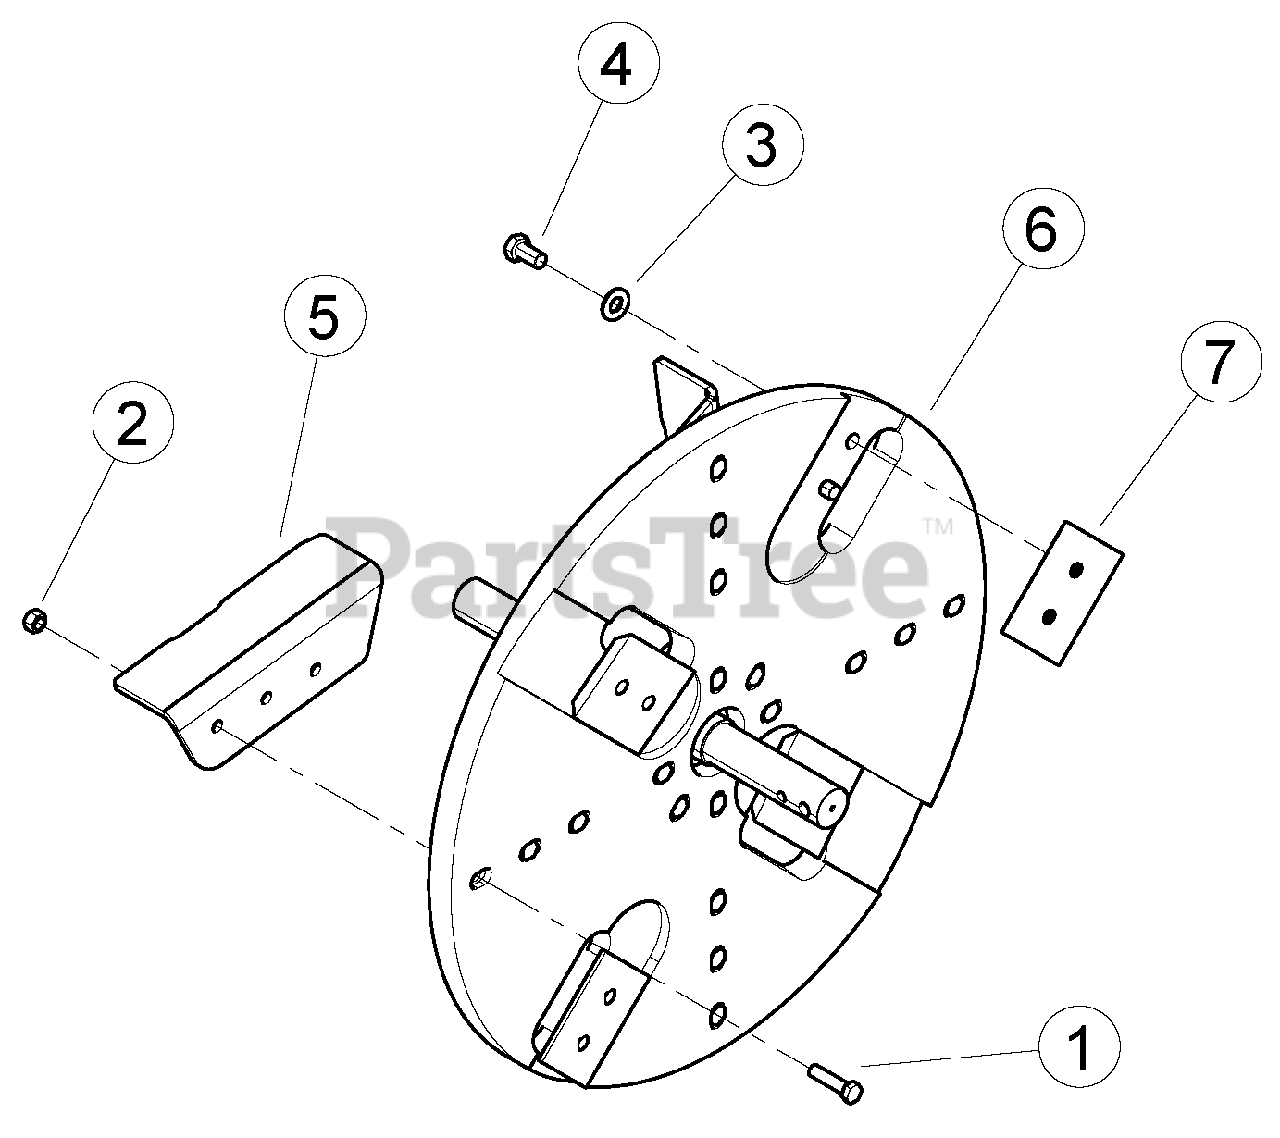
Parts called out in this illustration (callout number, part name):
1	BOLT, 1/2-13 X 2 GR5 HEX CAPSCREW
2	NUT, 1/2" CENTERLOCK GRB ZP
3	WASHER, 5/8 SAE HARDENED
4	BOLT, M16 X 2.0 X 30 HEX HD W/ PATCH
5	KIT, BIG CHIPPER FORMED PADDLES
6	ASSEMBLY, 9 INCH CHIPPER ROTOR
7	KIT, CHIPPER BLADE
